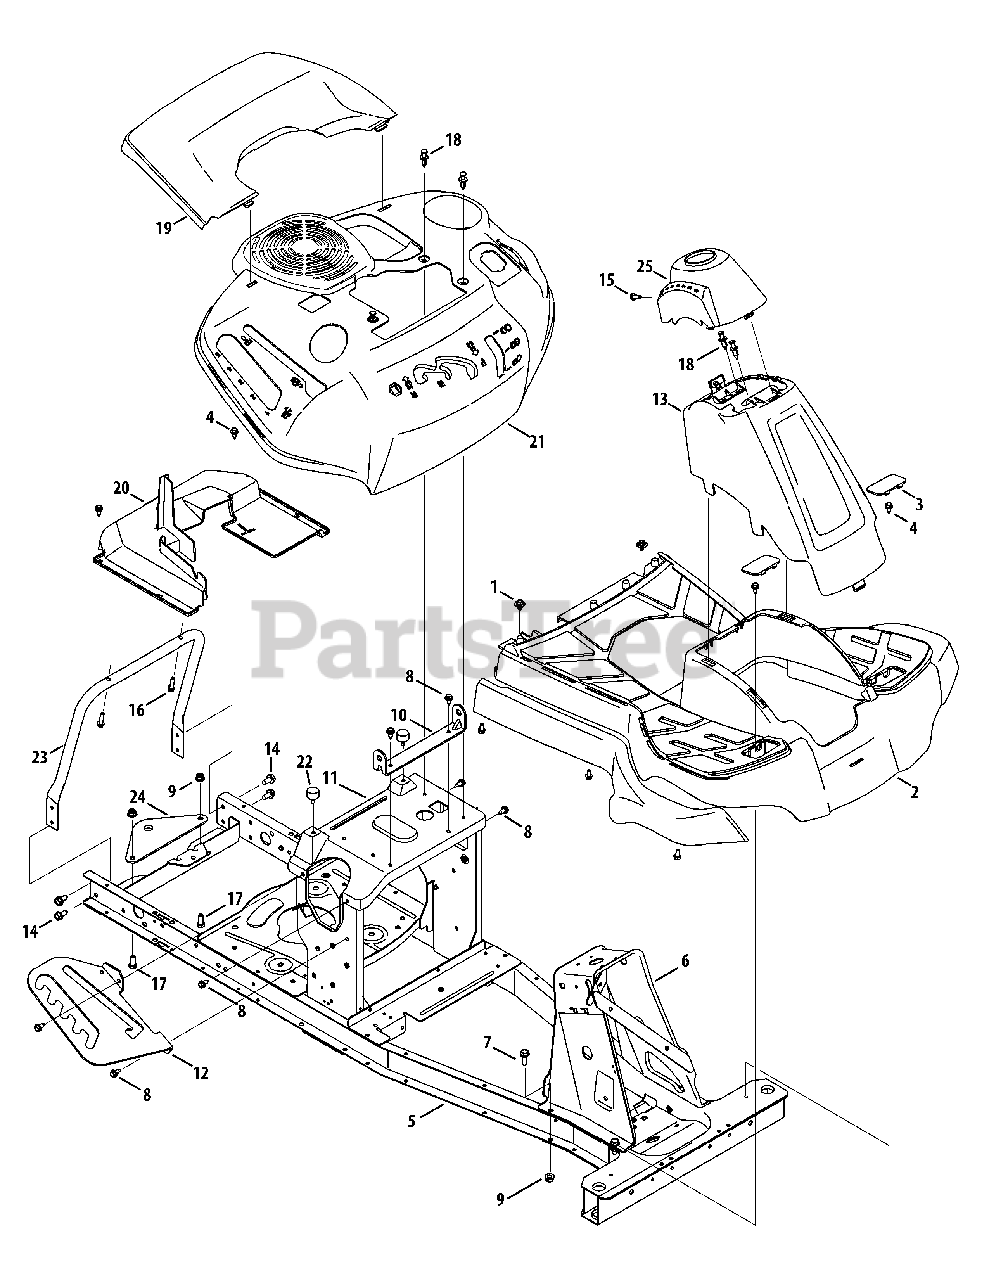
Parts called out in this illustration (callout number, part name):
1	Screw, 1/4-20 x .500
2	Running Board, RMC
3	Running Board Plug
4	Shoulder Screw, .368 X.113: 1/4-20
5	Frame Assembly
6	Column Assembly
7	Hex Washer Screw, 5/16-18 x .875
8	Tap Screw, 1/4-20, .625
9	Flange Locknut, 5/16-18
10	Seat Pivot Bracket
12	Deck Lift Index Bracket
13	Column Cover
14	Tap Screw, 5/16-18, .750
15	Machine Screw, 1/4-20, 0.750
16	Hex Screw, 1/4-15, 1.0
17	Hex Head Screw, 5/16-18, .75
18	Rivet, .3125
19	Rear Cover
20	Top Rear Drive Cover
21	Fender, (B&S Eng.)
22	Bumper, .62 Dia. x .50
23	Rear Cover Support Tube
24	Hitch Plate
25	Steering Column Cap (Orange)
